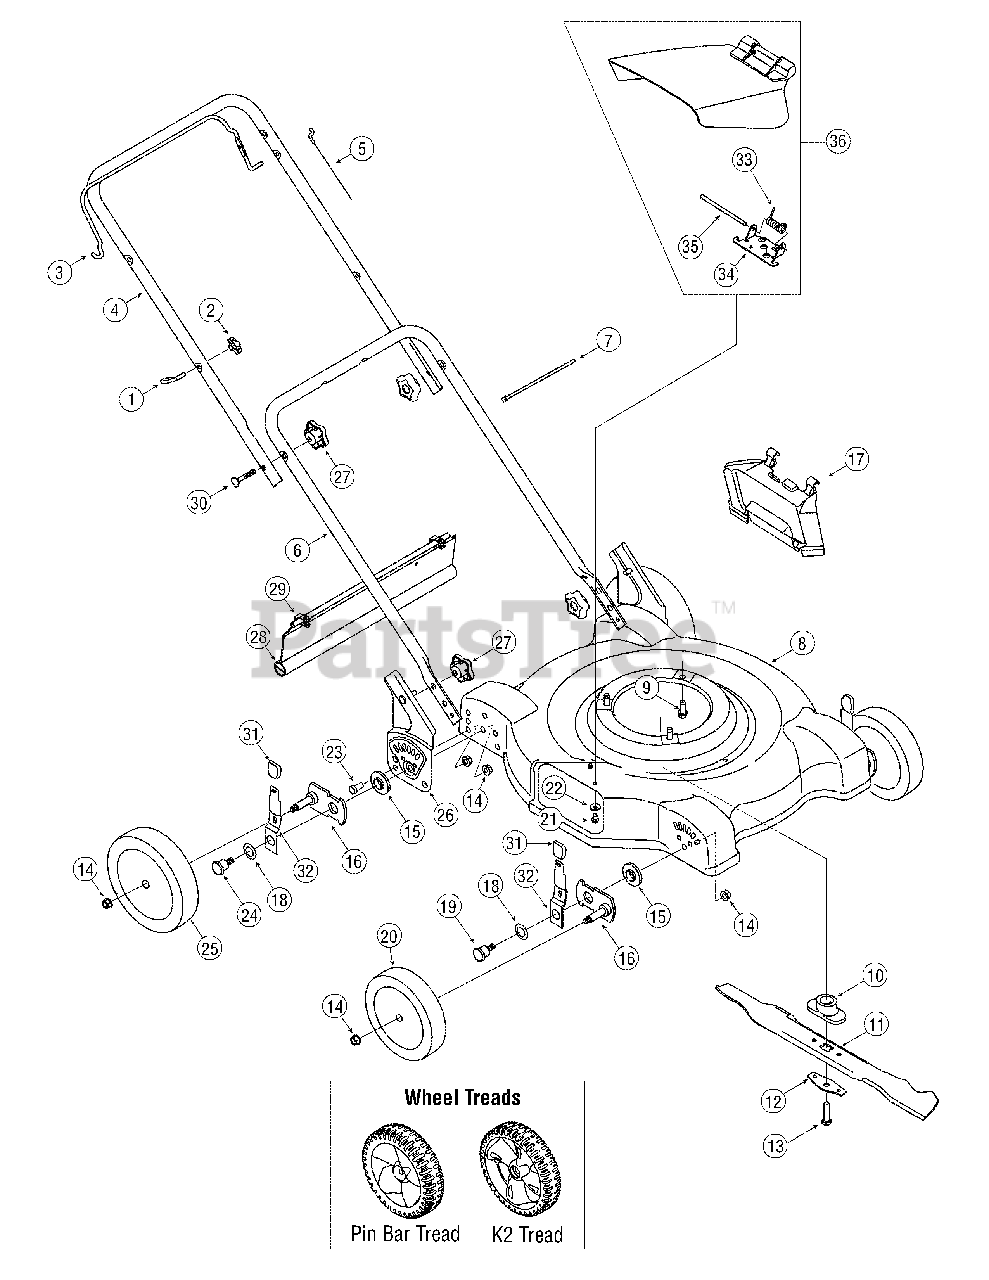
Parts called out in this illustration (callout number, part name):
1	Eye Bolt
2	Wing Nut
3	Blade Control Handle
5	Blade Control Cable - 37.25 inch
7	Cable Tie
9	TT Screw 3/8-16 x 1.0
10	Blade Adapter #6 X 1.19 w/star
10	Blade Adapter 25MM X 1.19
11	Standard Blade 22-inch
11	Mulch Blade 22-inch
12	Blade Bell Support
13	Screw 3/8-24 x 1.5
14	Lock Nut 3/8-16
15	Height Adjuster Bearing
16	Pivot Arm
17	Mulch Plug
18	Bell Washer .760 ID x 1.25 OD
19	Shoulder Screw
20	Front Wheel, 7 x 1.8, K2 Bar
21	TT Screw 1/4-20 x .5
22	Bell Washer .265 ID x .75 OD
23	Screw 3/8-16 x .75
24	Shoulder Screw
25	Rear Wheel, 8 x 1.8, K2 Bar
26	Handle Bracket Assembly RH
26	Handle Bracket Assembly LH
27	Star Knob
28	Trailshield
29	Hinge Clip
30	Carriage Bolt 5/16-18 x 2
31	Knob
32	Lever
33	Torsion Spring
34	Chute Hinge
35	Hinge Pin
36	Hinged Chute Deflector Assembly
